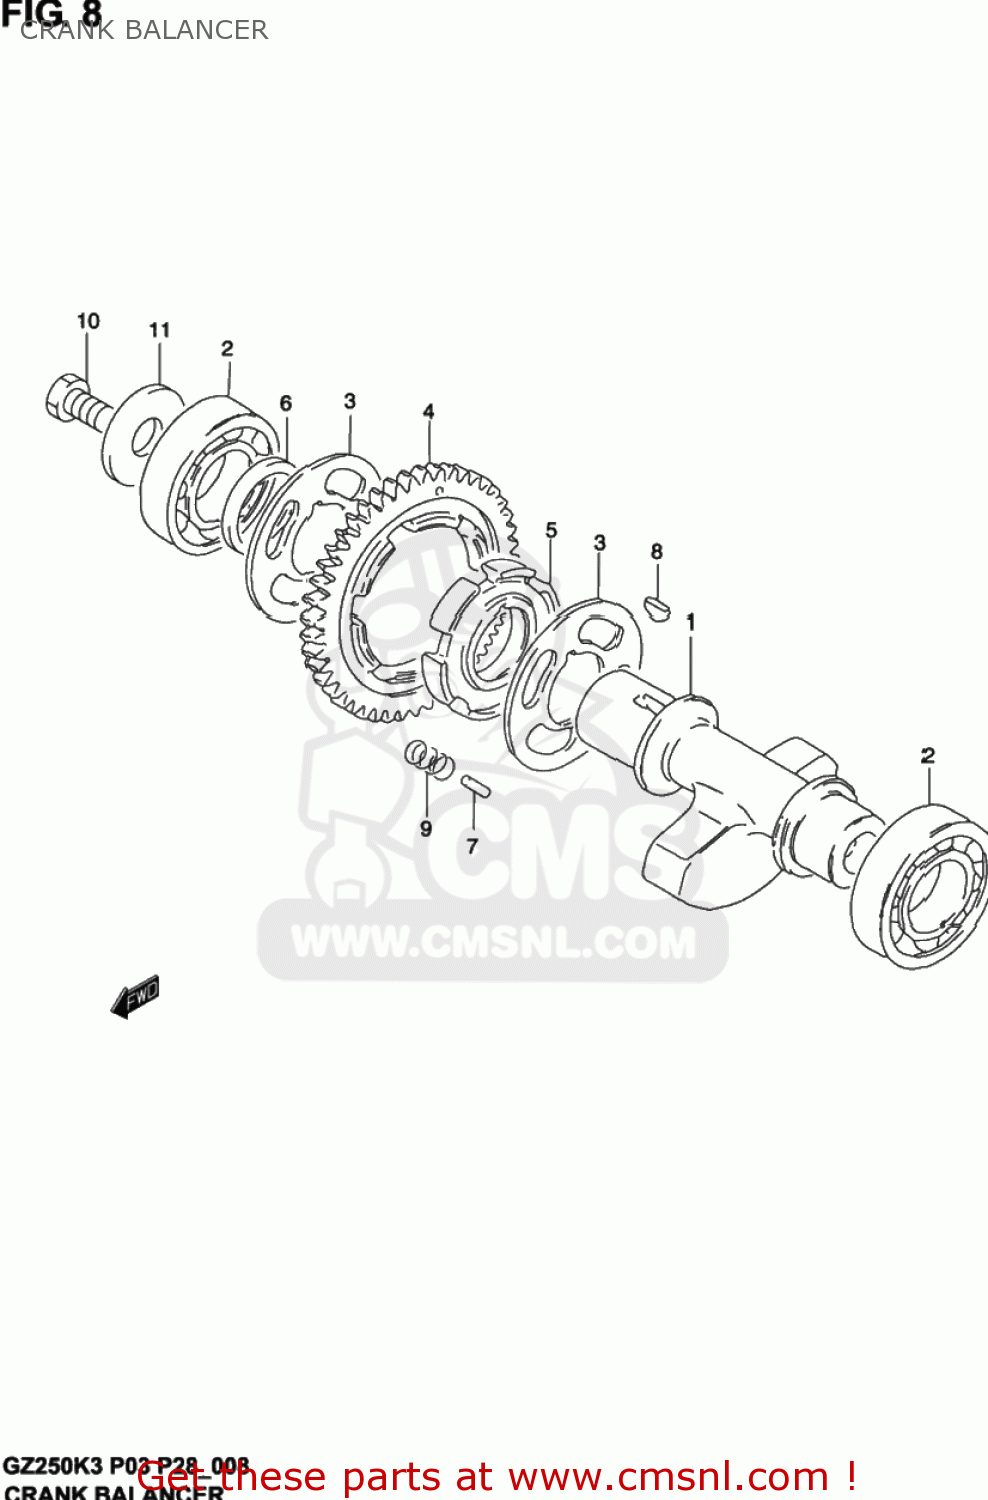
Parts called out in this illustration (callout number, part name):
1	SHAFT,CRANK BALANCER
2	BEARING(25X62X17)
3	WASHER
4	GEAR,CRANK BAL DRIVEN(NT:46)
5	RACE,CRK BAL DRIVEN GR INNER
6	SHIM(25X36X0.5)
7	PIN(4.5X9.5)
8	KEY
9	SPRING
10	Bolt
11	WASHER(12X40X2.5)
